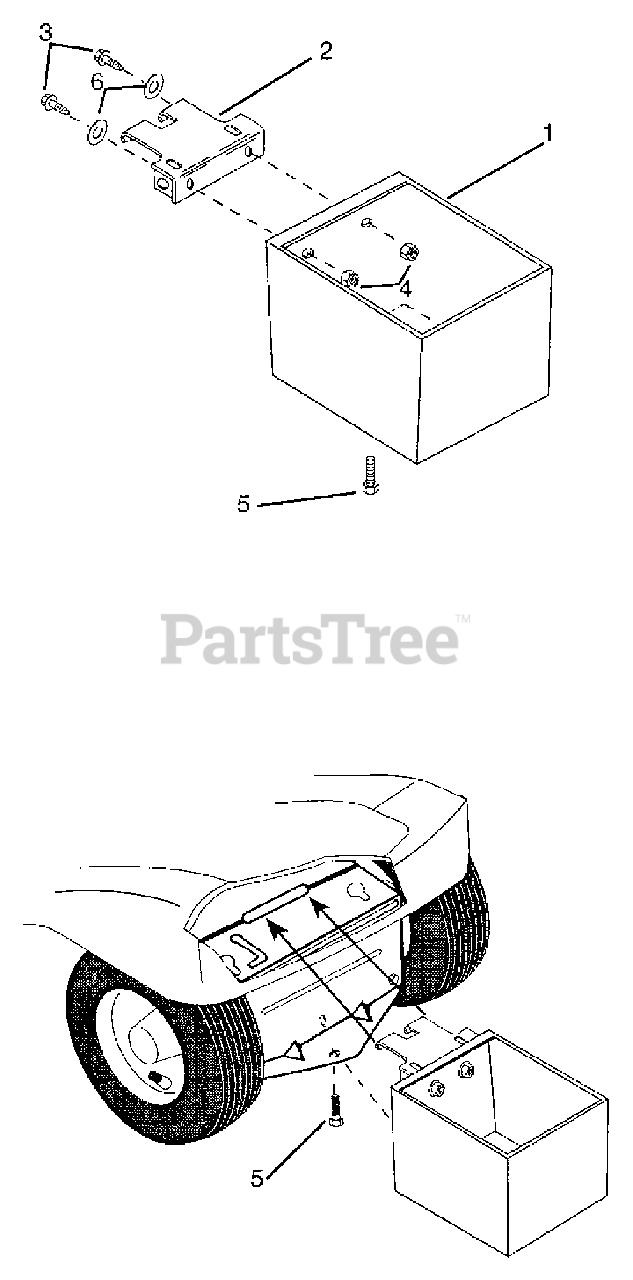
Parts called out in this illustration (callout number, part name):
1	Weight Box
2	Hook Mount
3	Bolt-Hex Head .31-18 x .75
4	Nut .312-18
5	Bolt-Hex .50-13 x1.00 Grade 2
6	Washer
